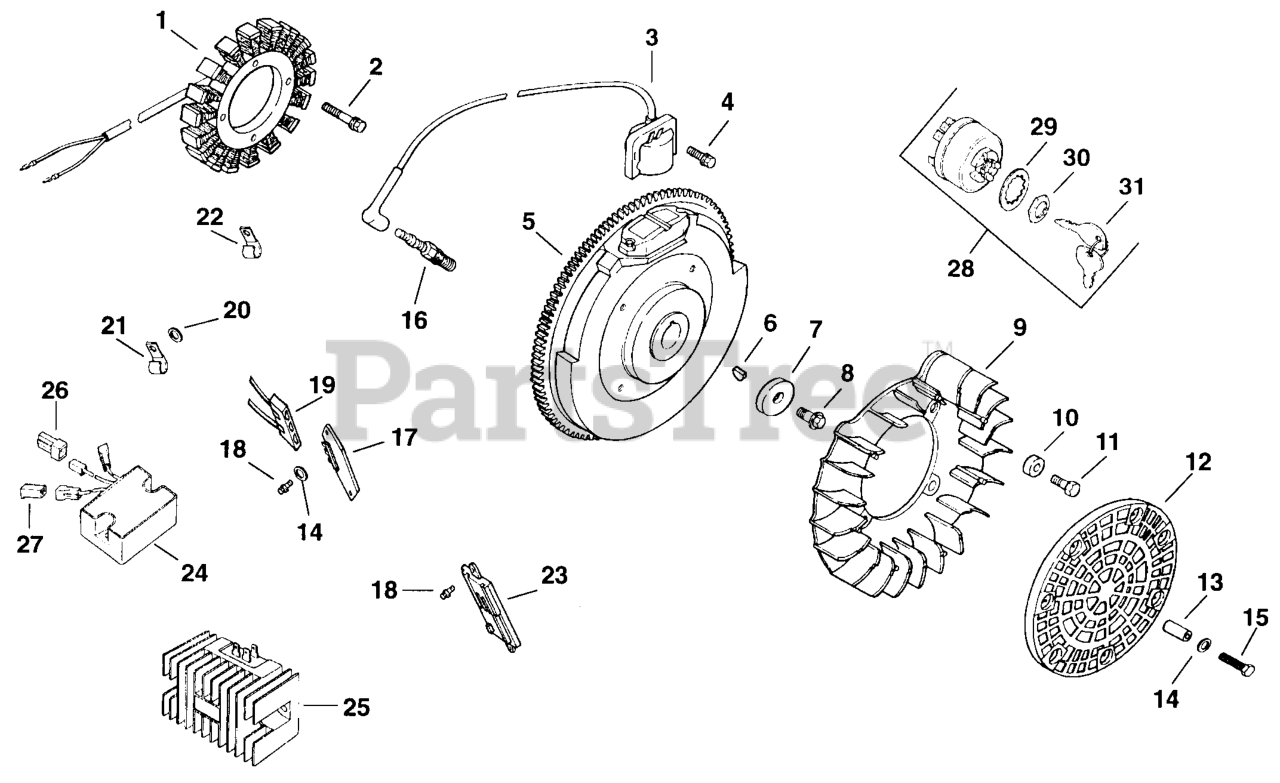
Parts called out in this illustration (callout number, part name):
1	KIT - USE 54 755 09
2	SCREW - USE M-548025
3	MODULE, IGNITION-USE 24 584 45-S
4	Screw, hex. flange M5x0.8x20
6	KEY, 3/16" X 5/8"
7	WASHER, FLAT 13/32"
8	SCREW, FLG M10X1.5X75
9	FAN (KM)-USE 24 157 15-S
10	BOLT - USE 25 086 47
11	SCREW - USE M-639016
14	WASHER, FLAT 3/16"
16	PLUG, SPARK (STD)
18	SCREW, PHL HD #11-16X7/8"
19	CONNECTOR, BODY (KM)-USE 25 155 41-S
20	WASHER, FLAT 1/4" (O.D. 1/2")
21	CLIP, CABLE
28	SWITCH ASSY, KEY (KM)-USE 25 099 32-S
29	WASHER, INTERNAL TOOTH
30	NUT, KEY SWITCH
31	KEY (KM)
2417621	KIT - USE 54 755 02
2451804	LEAD - USE 25 518 34
2451806-S	LEAD - DISCONTINUED
